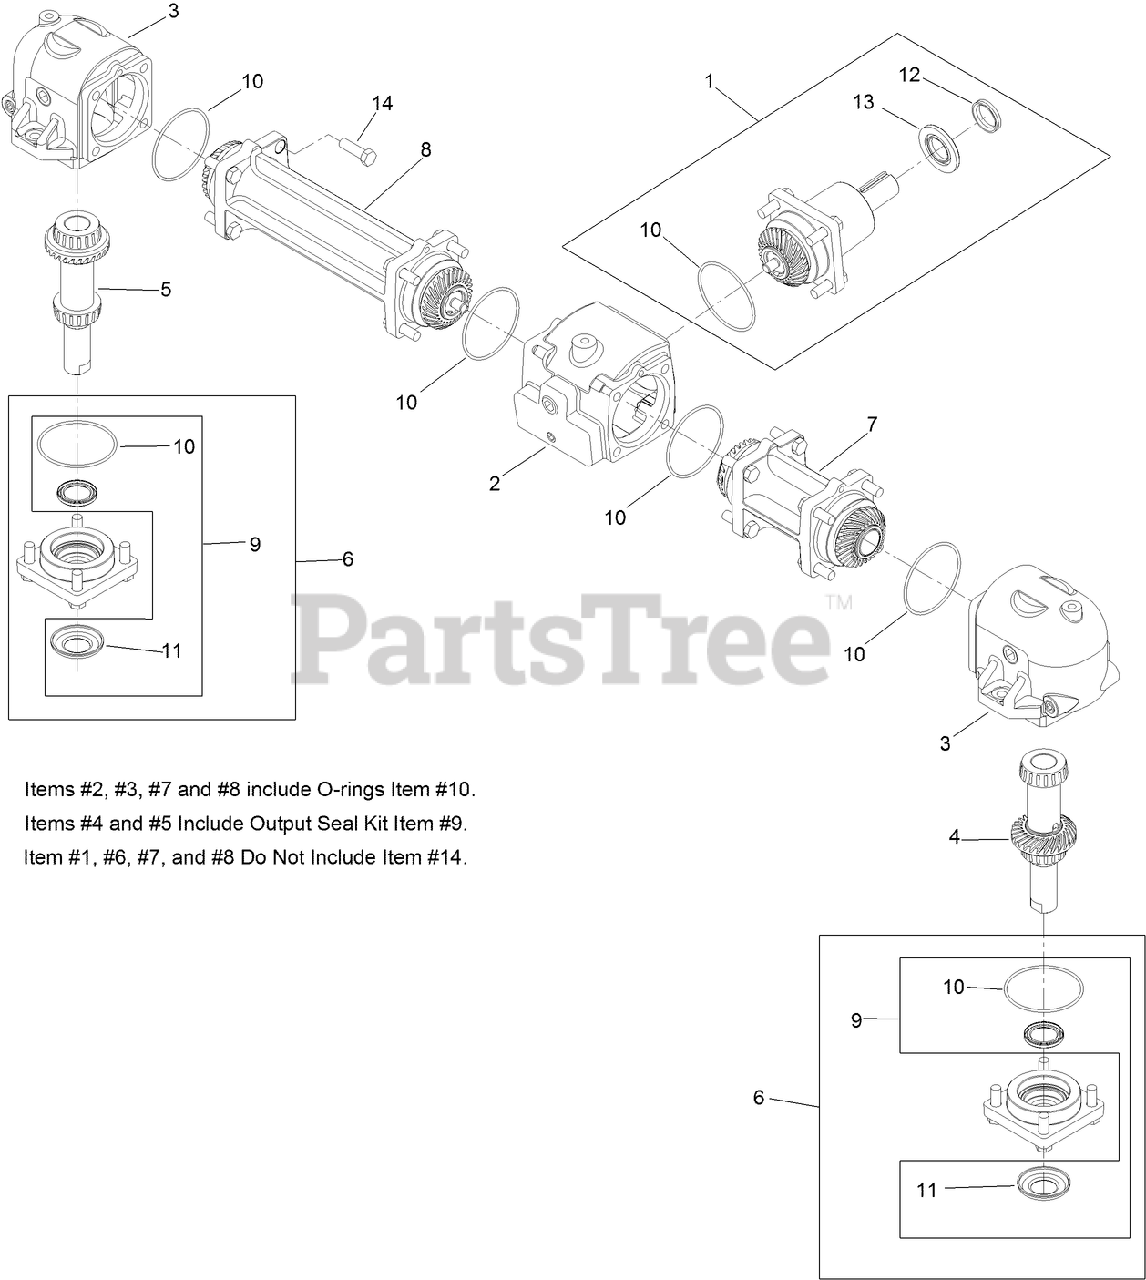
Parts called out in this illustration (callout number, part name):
1	INPUT PINION ASM
2	HOUSING-CENTER
3	HOUSING-END
4	LH OUTPUT SHAFT and GEAR ASM
5	RH OUTPUT SHAFT and GEAR ASM
6	CAP-OUTPUT
7	TUBE-CONNECTOR, SHORT
8	TUBE-CONNECTOR, LONG
9	OUTPUT SEAL KIT
10	SEAL-O-RING
11	WASHER-CUPPED
12	SEAL-V-RING
13	SEAL-INPUT
14	BOLT-BLADE
